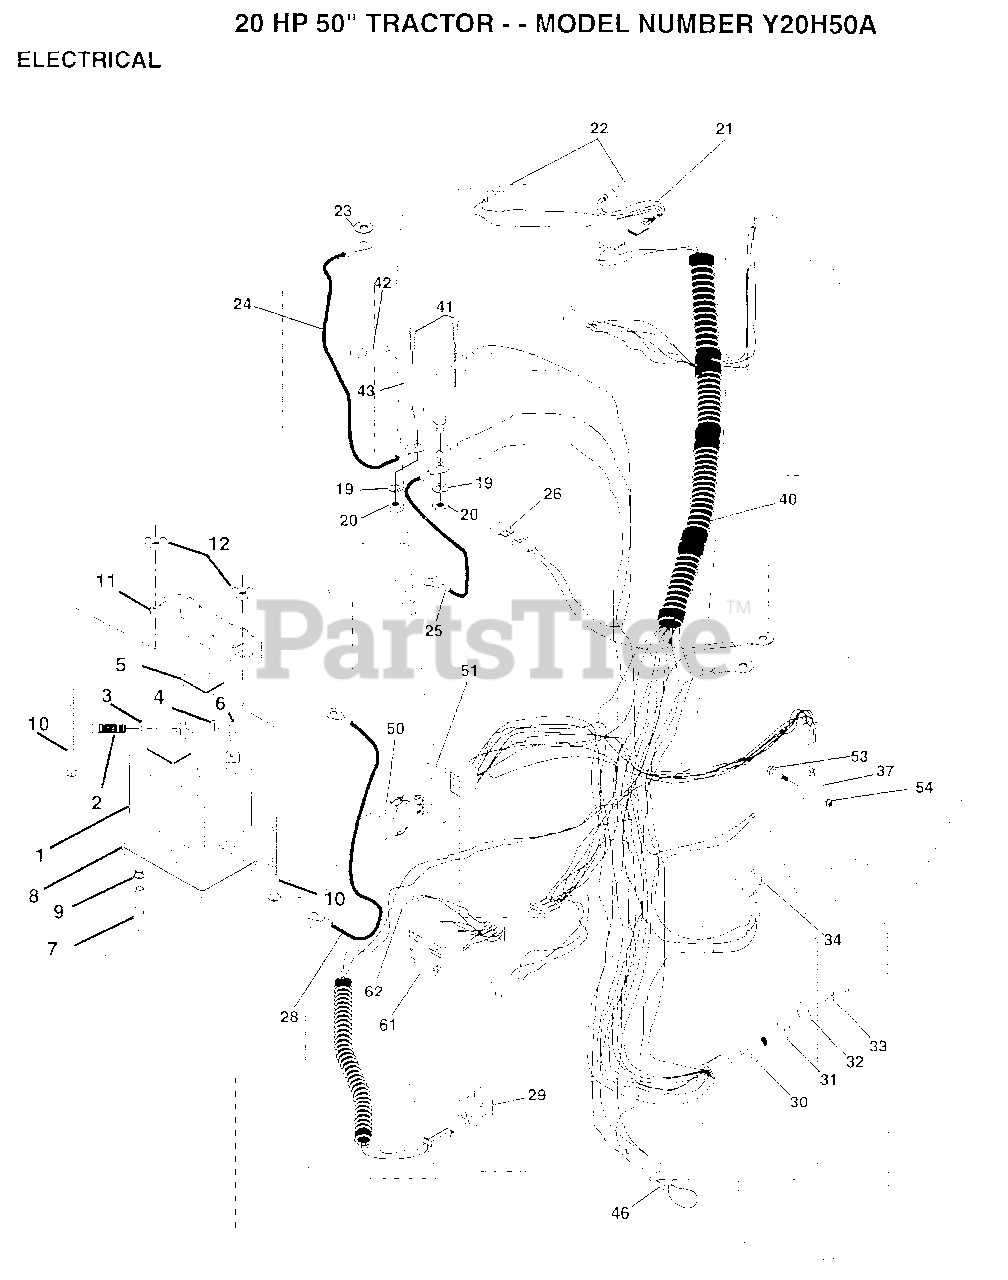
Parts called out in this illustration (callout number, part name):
2	BOLT LT
3	LOCKWASHER
4	WASHER
5	"CAP,BATTERY "
7	"DRAIN TU T, BATT"
8	"TRAY T, BATTERY"
9	HOSE CLAMP T
10	BOLT
20	NUT
22	HEADLAMP BULB
23	LOCKWASHER
24	"CABLE T, BATTERY"
25	CABLE-BATTERY T
26	FUSE HYT
28	CABLE T
29	SWITCH SEAT
32	COVER KEY SWITCH
33	KEY MLD GEN DELTA
34	SWITCH LT
37	SWITCH INTERLOCKT
40	HARNESS IGNITION
41	SCREW
46	PROTECTION LOOP
51	RING RETAIN PTO
53	SCREW
54	"NUT,KEPS"
61	LIGHT.PKG.ASM.
62	BULB LIGHT T
